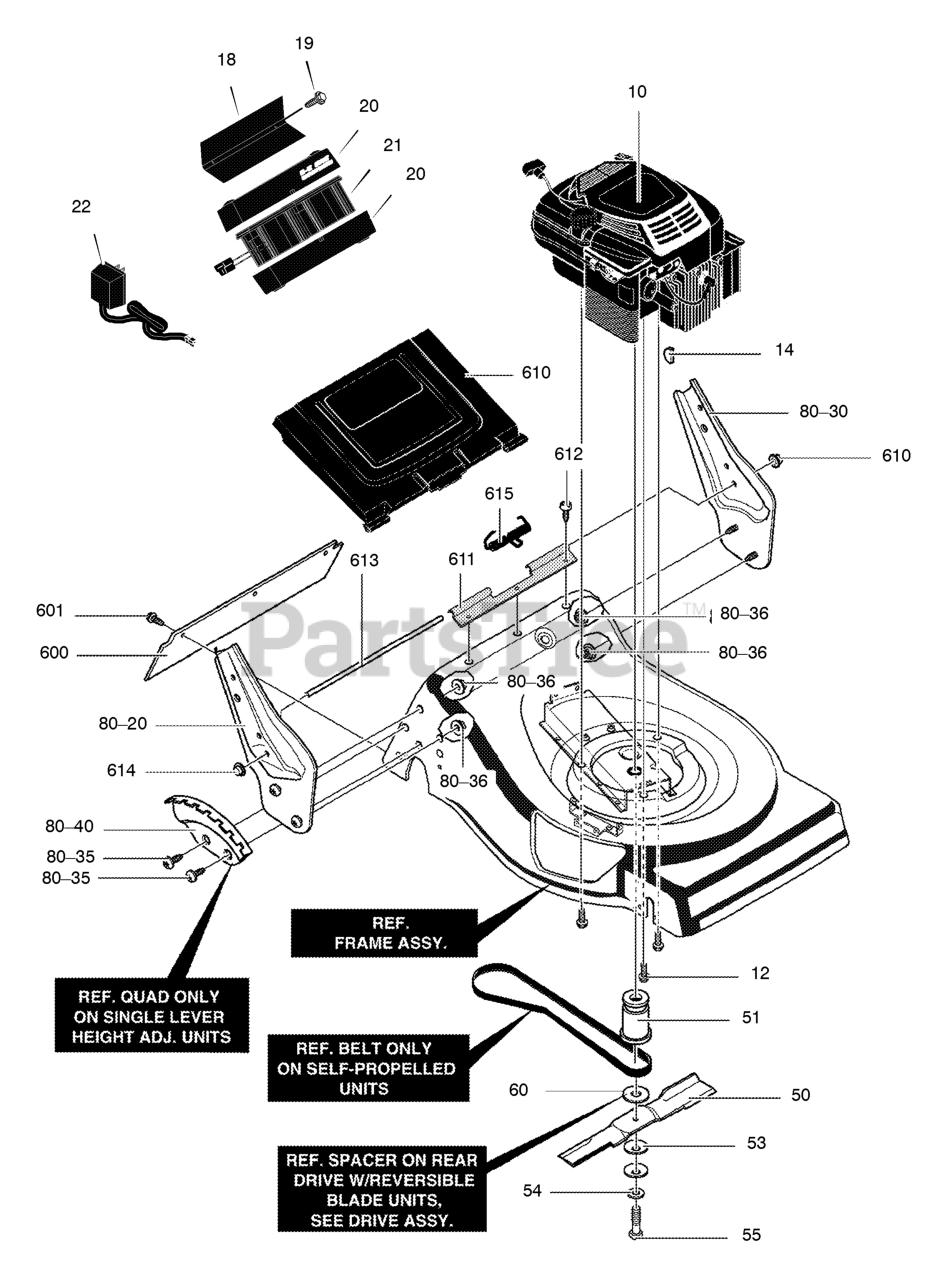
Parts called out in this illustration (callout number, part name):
10	Engine *
14	WOODRUFF KEY 505
18	BRACKET, BATTERY
19	SCREW *
20	CASE, BATTERY
21	BATTERY *
22	CHARGER, BATTERY
50	BLADE, 21" REVERSIBLE
51	ADAPTER, BLADE 21"
53	WASHER, BEVELLE
55	SCREW, 3/8-24 x 2.00
80-20	BRACKET, HANDLE RH
80-30	BRACKET, HANDLE LH
80-35	SCREW, 5/16-18 x 0.63
80-36	NUT, 5/16-16
80-40	INDEX, HEIGHT ADJ
256	BELT, V
600	DEFLECTOR, REAR
601	SCREW, 10-16X.50
610	DOOR, REAR 21
612	SCREW, 10-16X.50
613	ROD, PIVOT
614	CAP, PUSH ON
615	SPRING, TORSION
